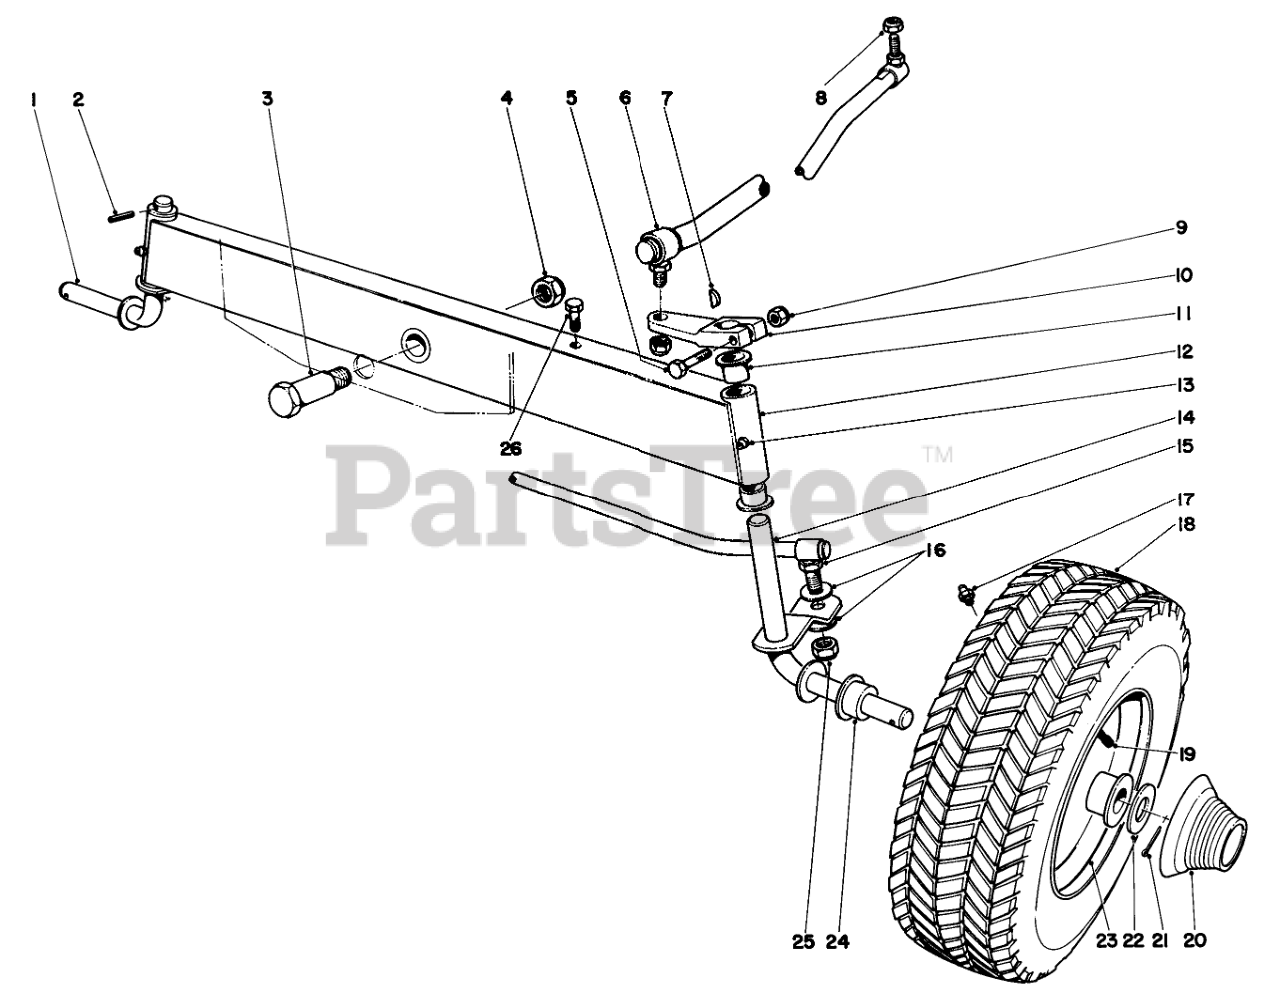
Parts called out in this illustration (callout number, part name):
1	Spindle
2	PIN-SPRING
3	Shoulder Bolt
4	1/2-13 CONELOCK NUT
5	SCREW-HH
6	Drag Link
7	KEY-WOODRUFF
8	Nut
9	NUT-LOCK, CONE
10	Arm Drag Link
11	3/4IDX1LG FLANGE BSHG
12	Front Axle Incl. Ref. #11
13	GREASE FITTING
14	Spindle L.H.
15	Tie Rod
16	WASHER
17	FITTING-GREASE
18	Tire
19	STEM-VALVE
20	FRONT HUB CAP
21	PIN-COTTER
22	Washer
24	Bushing
25	Nut
26	SCREW-HH, TAP
